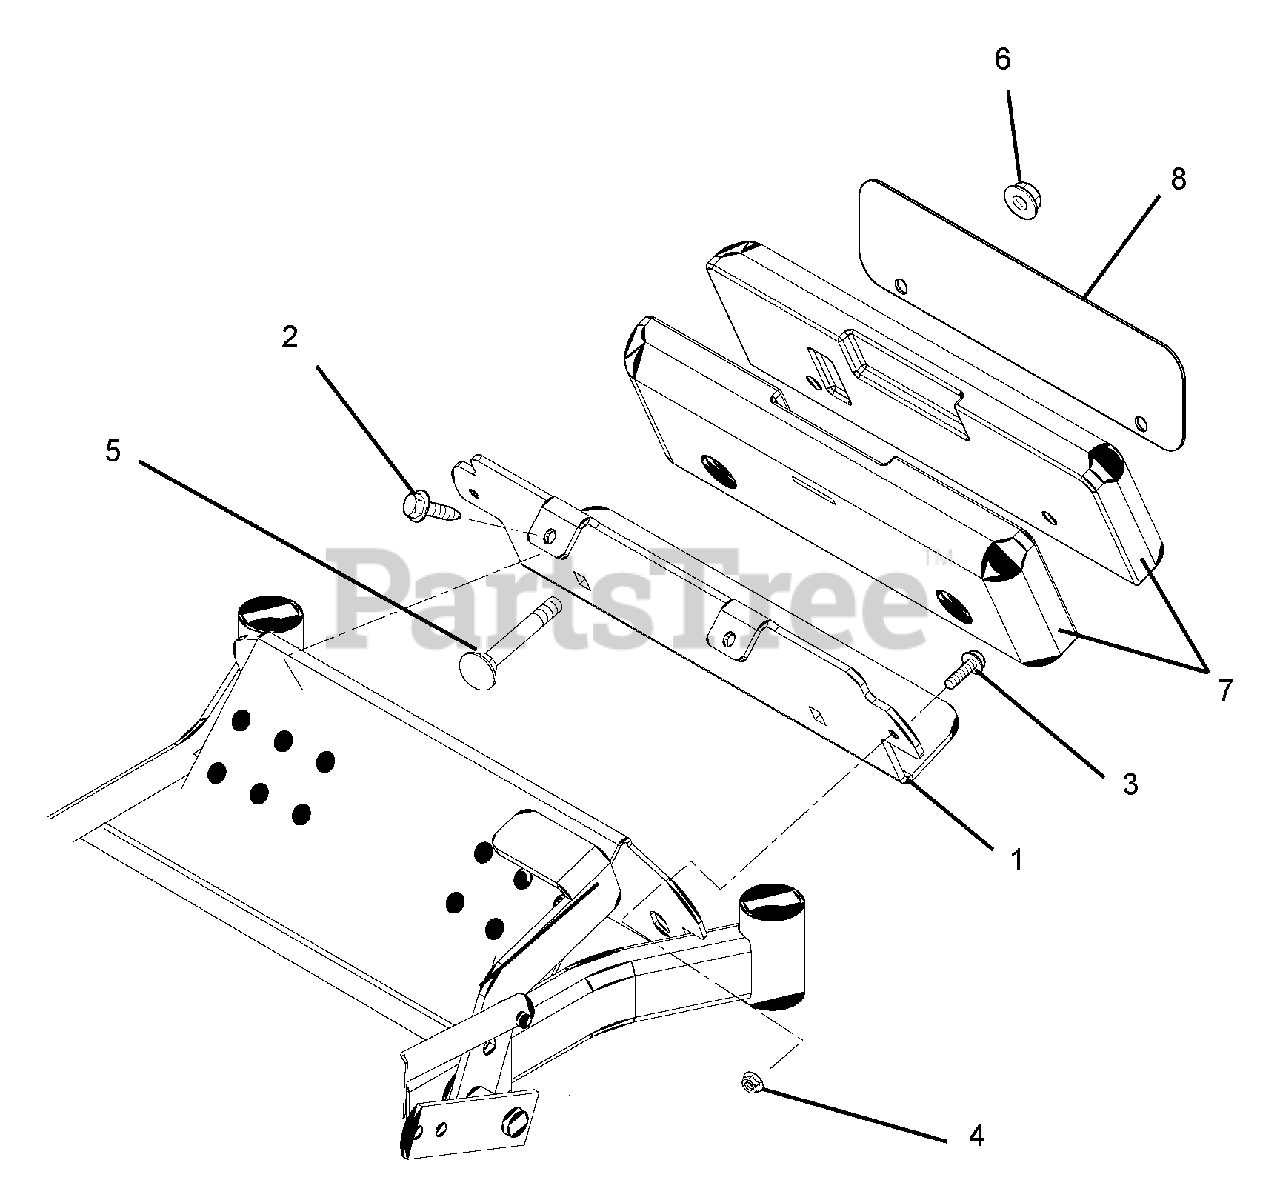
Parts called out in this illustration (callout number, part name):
1	Counterweight Bracket
2	Screw, .38-16 x .75 Self-Tapping
3	Bolt, Hex .38-16 x 1.25, Grade 5
4	Nut, Locking-Top-Flange .38-16
5	Bolt, Round Head Square Neck .50-13 x 5.00
6	Nut, Locking-Top-Flange .50-13
7	Counterweight
8	Decal Panel
